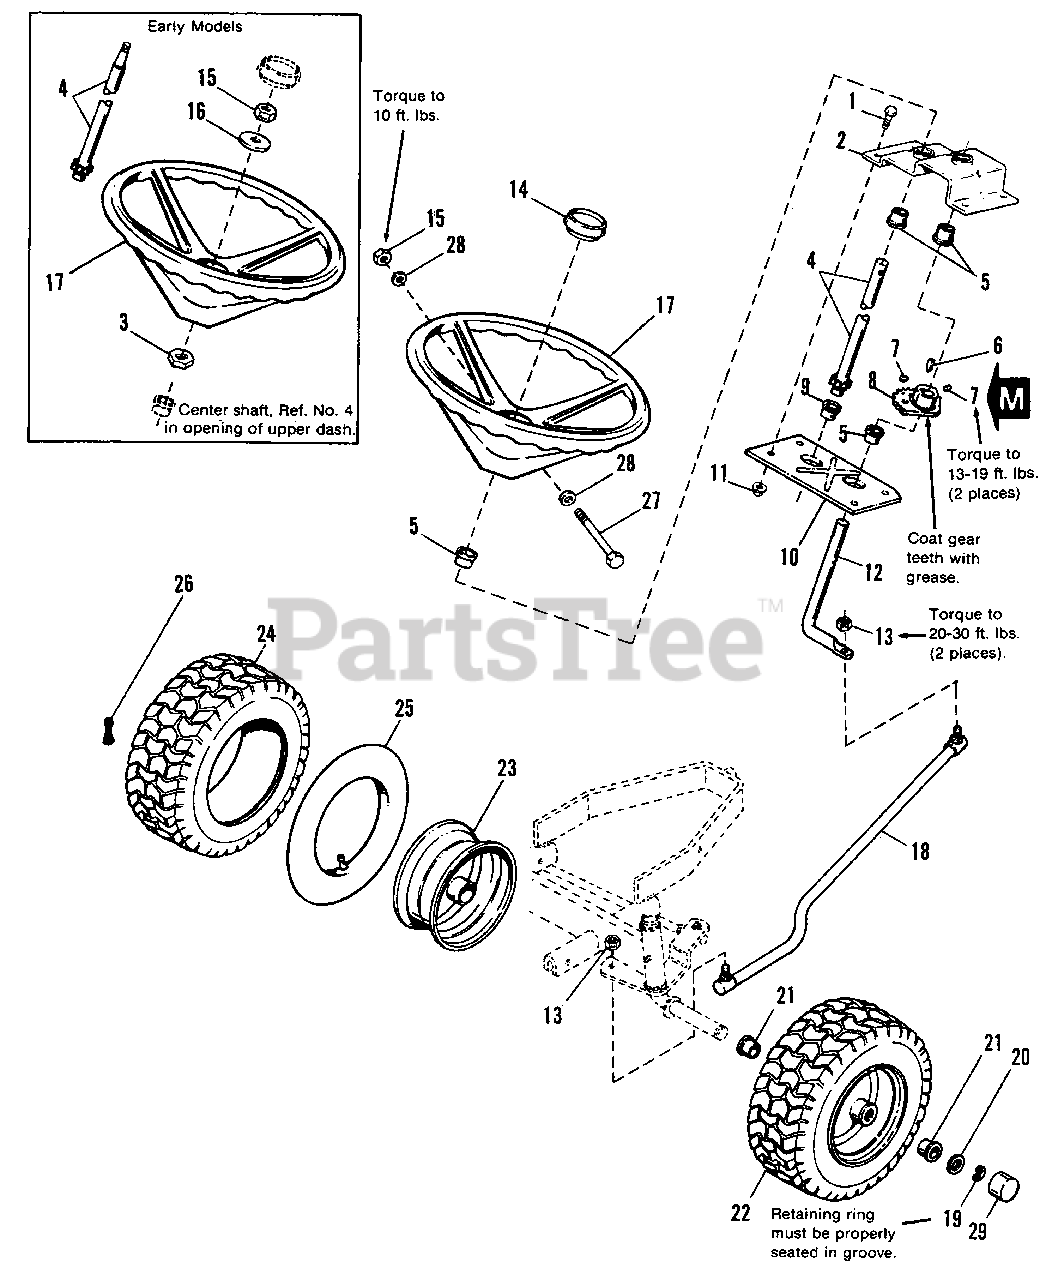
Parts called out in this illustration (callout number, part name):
1	CAPSCREW, 5/16-18 x 3/4
2	PLATE, Top, Steering
2	* ROD, Steering
3	* WASHER, Hex
4	* SHAFT ASSY., Steering
7	SETSCREW, 5/16-18 x 1/2
8	GEAR, Steering
10	PLATE, Base, Steering
11	LOCKNUT, Hex, Flange, 5/16-18
12	* ROD, Steering
13	NUT, Special
14	CAP, Steering Wheel
15	LOCKNUT, 5/16-18
16	* WASHER, Compression
17	* WHEEL, Steering
19	E-RING, Ext., 3/4
22	WHEEL & TIRE ASSY., 15 x 6.00-6 (Includes Ref. No. 21, 23, 24, 25 & 26)
23	WHEEL
24	TIRE, 15 x 6.00-6 (Carlisle)
25	TUBE, 4.10/3.50-6 (Service Only)
26	STEM, Valve & Cap
27	BOLT, Hex 5/16-18 x 3 1/2
28	WASHER, Plain 5/16
29	CAP, Hub, Thrd.
